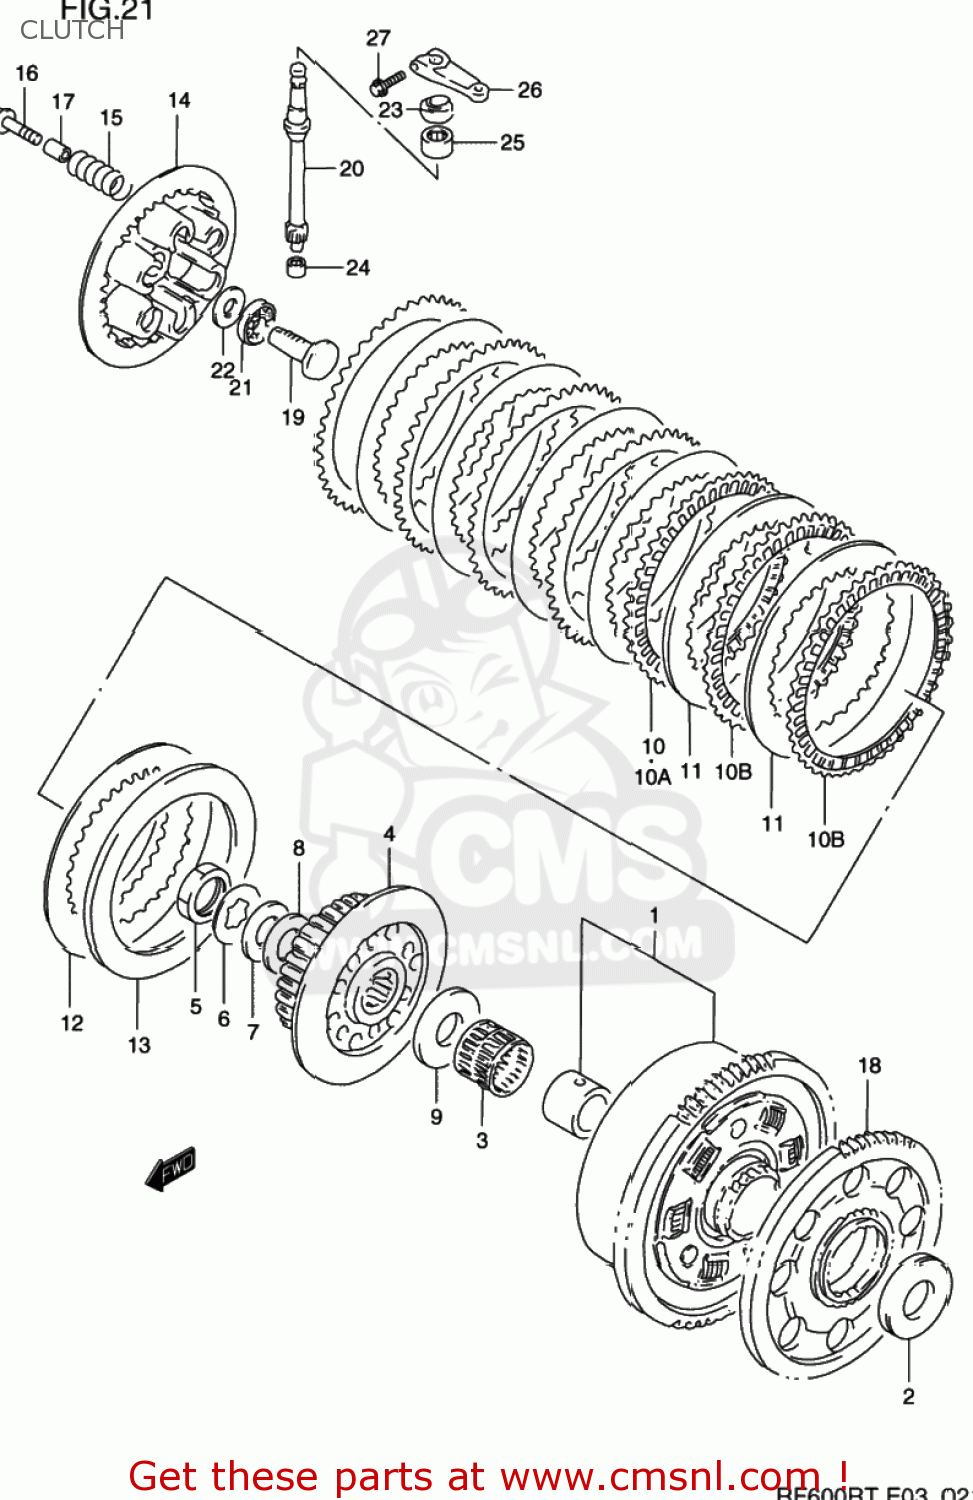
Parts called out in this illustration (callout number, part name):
1	GEAR ASSEMBLY,PRIMARY DRIVE
2	WASHER(25X54X2.5)
3	BEARING(35X40X35.8)
4	HUB,CLUTCH SLEEVE
5	NUT
6	WASHER,LOCK
7	WASHER
8	WASHER
9	WASHER(25X50X2.5)
10	PLATE,CLUTCH DRIVE
10A	PLATE,CLUTCH DRIVE
10B	PLATE,CLUTCH DRIVE (NAS)
11	PLATE,CLUTCH DRIVEN
12	PLATE,CLUTCH DRIVEN (NAS)
13	SPACER,CLUTCH PLATE
14	DISC,CLUTCH PRESSURE
15	SPRING
16	BOLT(6X40)
17	SPACER(6.2X12X16)
18	GEAR,GENERATOR DRIVE
19	RACK,CLUTCH RELEASE
20	PINION,CLUTCH RELEASE
21	BEARING(15X28X2)
22	WASHER(15.5X28X1)
23	OIL SEAL
24	BEARING 10X14X10
25	BEARING(15X22X12)
26	ARM,CLUTCH RELEASE
27	BOLT
